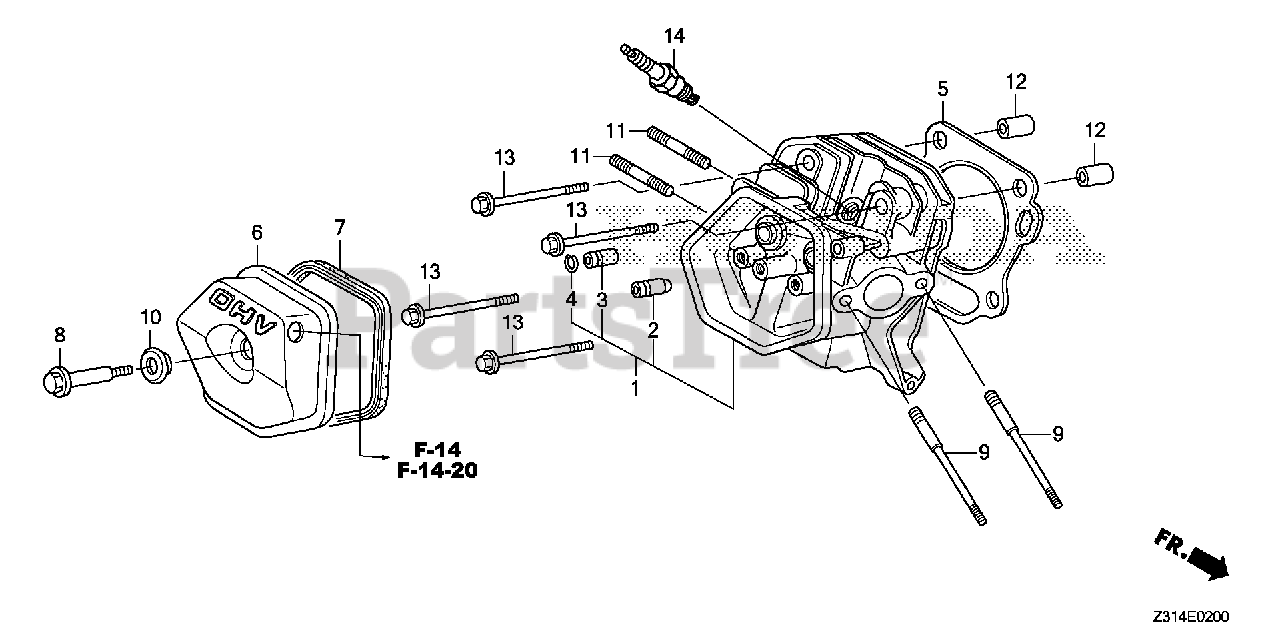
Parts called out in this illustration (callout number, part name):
1	CYLINDER HEAD
2	GUIDE, VALVE (OS)
3	GUIDE, EX. VALVE (OS)
4	CLIP, VALVE GUIDE
5	GASKET, CYLINDER HEAD (NIPPON LEAKLESS)
6	COVER, HEAD
7	GASKET, CYLINDER HEAD COVER
8	BOLT, HEAD COVER
9	BOLT, STUD (8X115)
10	WASHER, HEAD COVER
11	BOLT 2, STUD (8X32)
12	PIN A, DOWEL (12X20)
13	BOLT, FLANGE (10X80)
14	SPARK PLUG (BPR5ES) (NGK)
